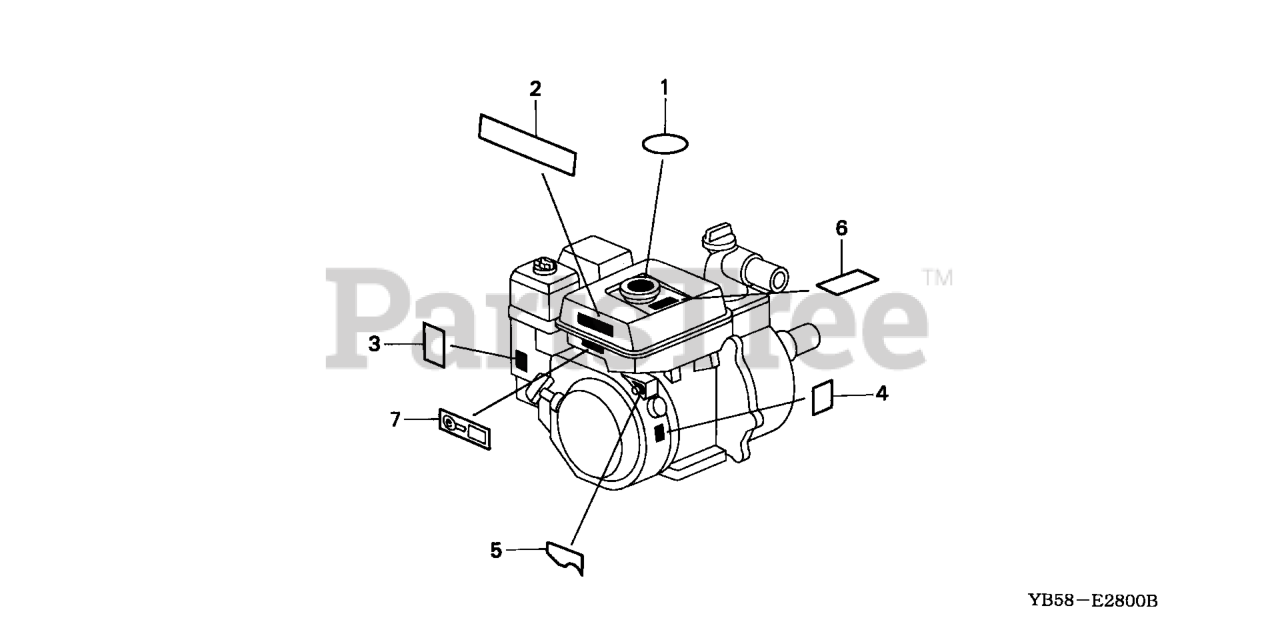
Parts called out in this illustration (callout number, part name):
2	LABEL, CAUTION (ENGLISH, ETC.)
3	MARK, CHOKE
6	MARK, OIL ALERT (ENGLISH)
7	LABEL (E-SPEC)
